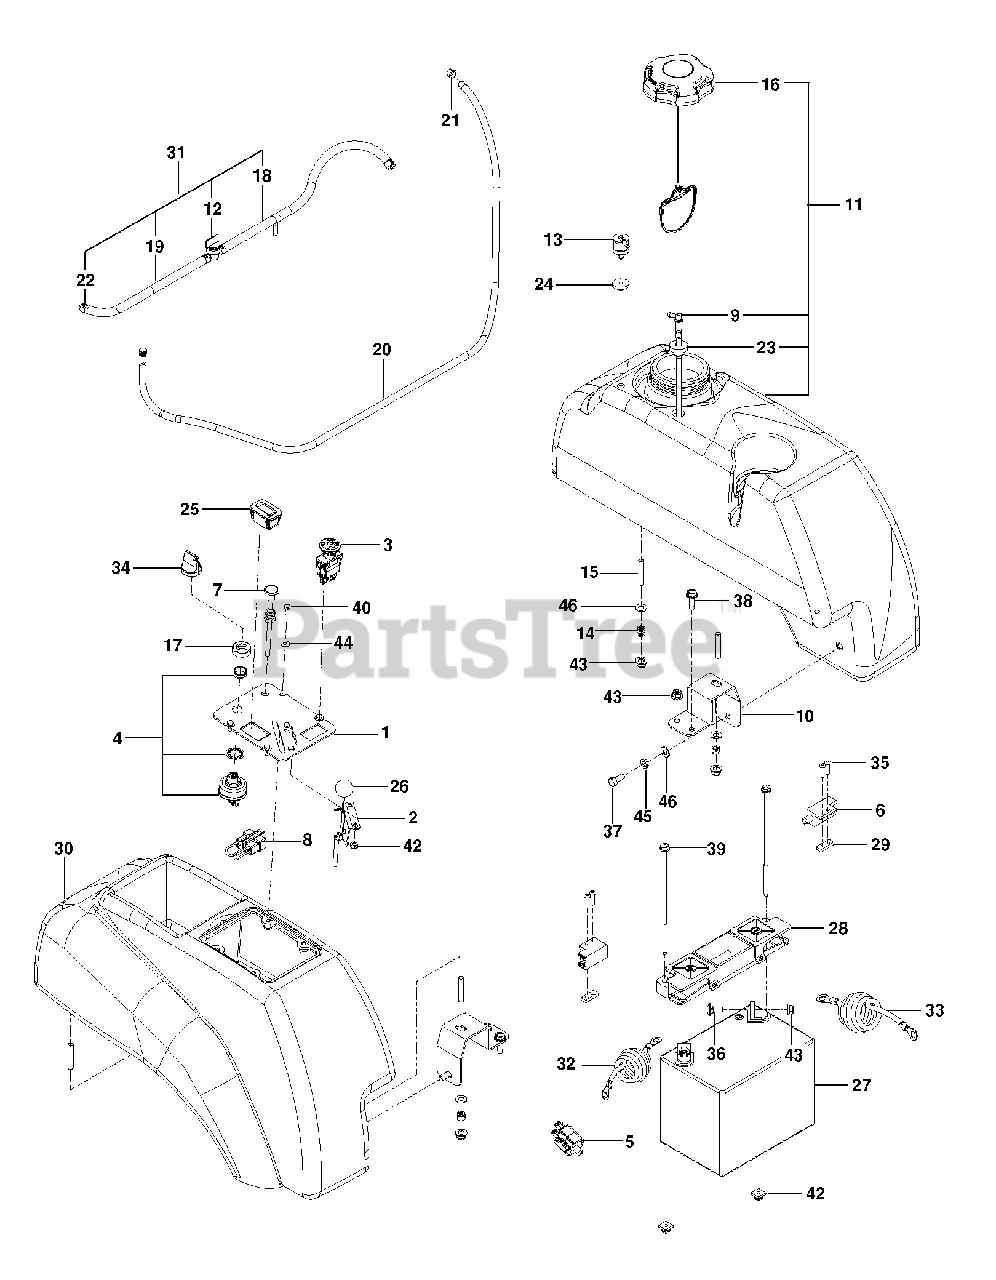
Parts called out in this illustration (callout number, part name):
1	PLATE, CONSOLE, BLK
2	THROTTLE CONTROL W/BALL KNOB
3	SWITCH, PTO 10 AMP
4	SWITCH, IGNITION, INDAK
5	SWITCH, BRAKE 3P
7	CABLE, CHOKE KAWASAKI
8	PLUG, TIMER
9	FITTING, FUEL
10	SUPPORT, TANK, BLK
12	FUEL VALVE
13	VALVE.FUEL.CHECK
15	STUD, 5/16C
16	CAP, FUEL
18	HOSE, FUEL .25 ID X 26"
19	GAS LINE 10"
21	CLAMP, HOSE
22	HOSE CLAMP
23	RUBBER GROMMET
24	GROMMET, CHECK VALVE
26	KNOB ROUND BALL
28	BATTERY HOLD DOWN
29	TAPPED PLATE
30	CONSOLE, RT-BLK
32	POST.CABLE LONG
33	NEG. CABLE, 28"
34	KEY, IGNITION
35	SCR #10-24 X .75 SKT HD BLK
36	BOLT 5/16C X 3/4" CARRIAGE
37	HCS 5/16C X 3/4
39	BOLT - 1/4-20 X 7.5
40	HCS #10-24 X 1/2
41	SCR #10-24 X .75 SKT HD BLK
42	PUSH NUT-NYLON
43	5/16-18 NYLOC FLANGE NUT
44	WASHER #10
45	WASHER 5/16 LOCK
46	FLAT WASHER 5/16 SAE
